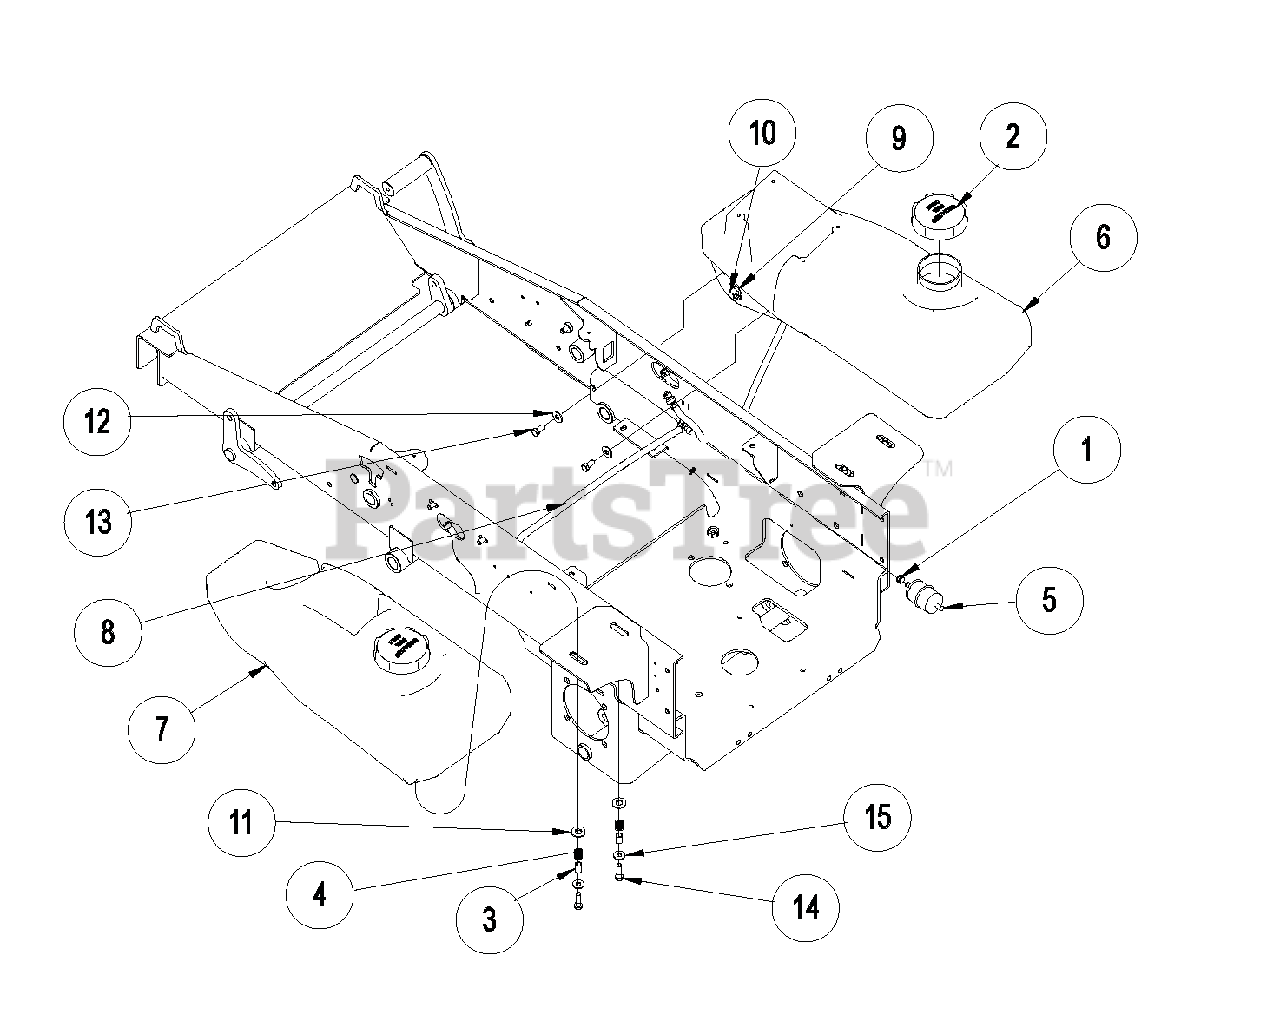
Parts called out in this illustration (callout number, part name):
1	CLAMP, HOSE - 1/2" SPRING
2	CAP, FUEL S/O
3	SPACER, GAS TANK ATTACHMENT
4	SPRING, COM .660 X .067 X .625
5	FUEL FILTER S/O
6	TANK, RH FUEL W/GRAPHICS
7	TANK, LH FUEL W/GRAPHICS
8	ASSY, FUEL LINE W/CHECKVALVES
9	GROMMET, RUBBER TANK S/O
10	FTG, 90 1/4HOSE X 1/2HOSE S/O
11	WASHER, .500X1.00X.105 FLAT Y
12	WASHER, .375 REG FLAT Y
13	BOLT, 3/8-16X.750 HEX 5 Y
14	BOLT, 3/8-16X1.25 HEX 5 Y
15	WASHER, .313 REG FLAT Y
